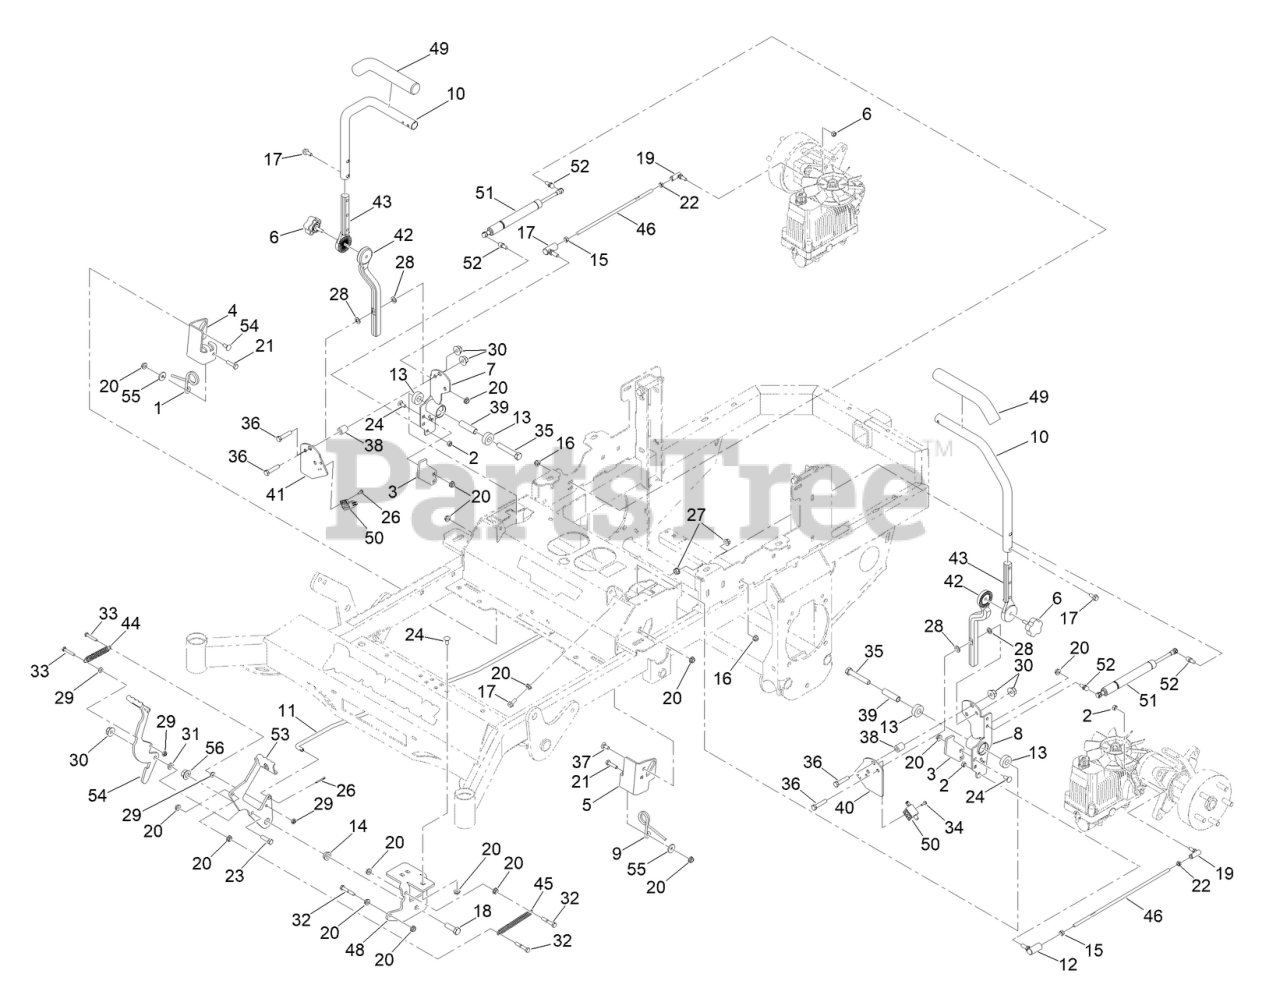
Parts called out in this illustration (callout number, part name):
1	SPRING-TORSION
2	5/16-24 NYL INS L/N GR.8 ZC/YEL
3	REVERSE DETENT KICK PLATE
4	REVERSE DENTENT SPRING BASE (RH)
5	REVERSE DENTENT SPRING BASE (LH)
6	5/16-18 X 1 SL 5-LOBE MALE ST KNOB 1.90
7	MOTION CONTROL BRKT
8	MOTION CONTROL BRKT
9	SPRING- LT REVERSE DETENT
10	MOWER DRIVE HANDLE TUBE ABC
11	MWR BRAKE LINKAGE
12	CONTROL ARM ROD END LT
13	5/8IN ID X 1-3/8IN OD X 7/16IN THK BRG
14	1/2IN ID X 3/4IN OD X 3/8IN FLANGE BUSH
16	NUT-HF, NI
17	SCREW-HHF
18	SCREW-HH
19	BALLJOINT-RH (W/GROMMET)
21	SCREW-HH
22	NUT-JAM
23	SCREW-HH
24	BOLT-CARR
26	PIN-COTTER
27	3/8-16 HEX FLANGE NUT W/SERR ZINC YELLOW
28	3/8 X 3/4 BRONZE WASHER
29	1/4-20 HEX FLANGE NUT
30	3/8-16 NYLON INSERT FLANGE L/NUT YZ
31	3/8 ID X 3/4 OD X .125 THK BRONZE WASHER
33	1/4-20 X 1-1/4 HEX C/S GR 2 ZINC
34	8-32 X 1/2 IND. HWH SLOT TYPE F TCS ZINC
35	1/2-13 X 3 HEX C/S GR 5 ZINC W/LOCTITE
36	3/8-16 X 1-3/4 HEX C/S GR 2 ZINC
37	5/16-18 X 1 CARRIAGE BOLT GR 8 YZ
38	MWR DRIVE ARM SPACER
39	MWR DRIVE ARM HUB / DECK LIFT ARM SPACER
40	LT CONTROL ARM LIMIT SWITCH PLATE PAINT
41	RT CONTROL ARM LIMIT SWITCH PLATE PAINT
42	ADJUSTABLE LWR DRIVE ARM
43	ADJUSTABLE UPP DRIVE ARM
44	MWR BRAKE PEDAL RELEASE SPRING
45	2020 MWR BRAKE PEDAL TENSION SPRING
46	TRANS DRIVE ARM LINKAGE STANDARD TRANS
48	MWR FRAME BRAKE MTG BRKT PAINT
49	CONTROL ARM HANDLE GRIP
50	NO PLUNGER LIMIT SWITCH
51	CONTROL ARM DAMPER
52	5/16-18X1.286 DAMPER BALL STUD (.562 TL)
53	MWR BRAKE LOCK LEVER ASSY PAINTED
54	MWR BRAKE UNLOCK LEVER ASSY PAINTED
55	STRIKER POST FENDER WASHER
56	NUT-LOCK
